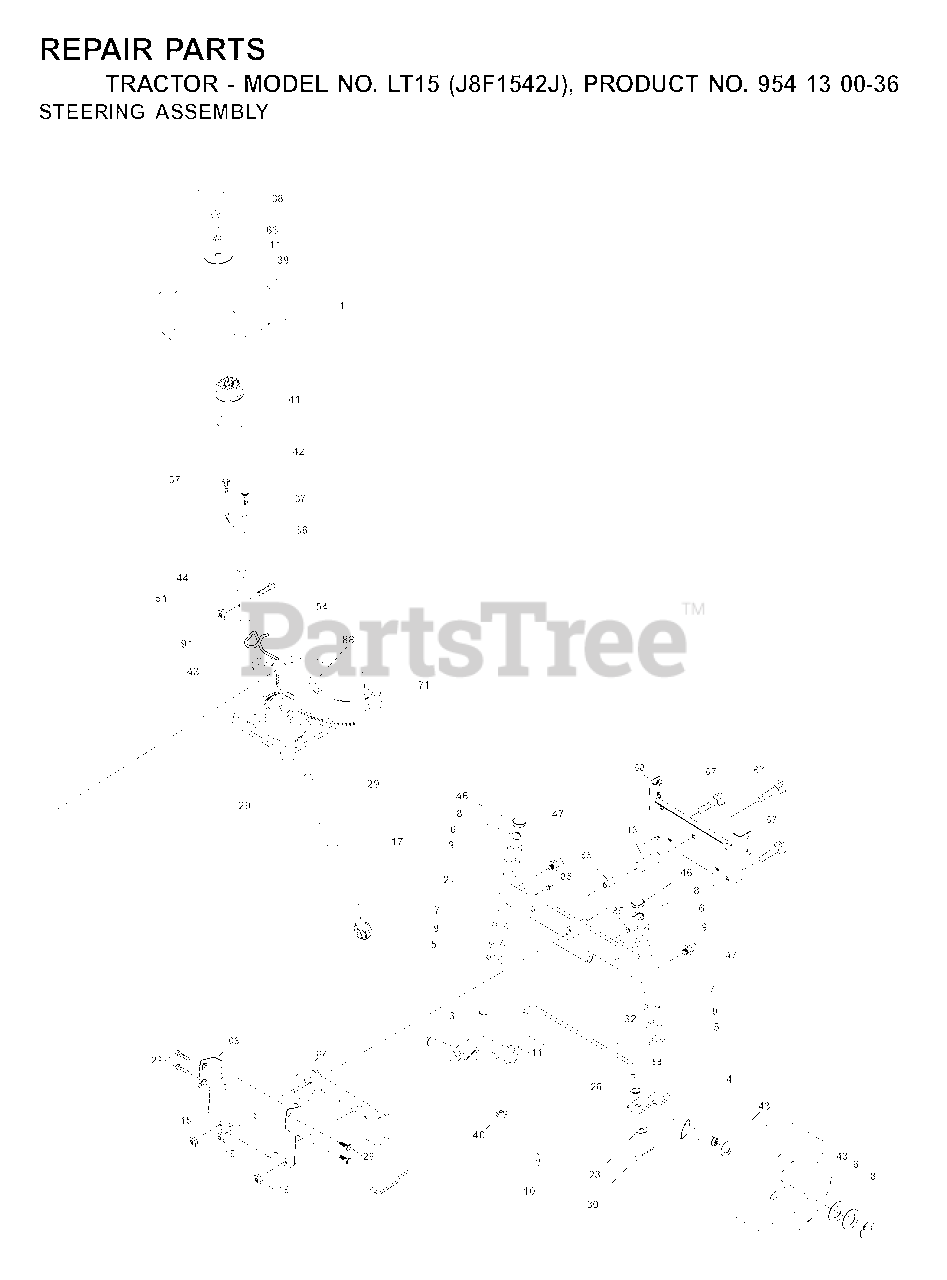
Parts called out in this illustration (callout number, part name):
2	AXLE ASSY
3	SPINDLE.ASM.LH.15"TIRES
4	SPINDLE.ASM.RH.15"TIRES
8	RING CLIP
9	BRNG T
10	DRAGLINK.15".TIRES.2001
11	WASHER, LOCK 3/8
13	TUBE, PIVOT AXLE
15	NUT
17	SHAFT ASM
26	BUSHING.DRAGLINK
28	WASHER
29	SCREW 3/8-16X3/4
30	COTTER PIN
32	TIE ROD
36	BUSHING, STEERING
39	WASHER 13/32 X 2-3/8 X 12 GA
40	GRIPCO NUT
41	STEERING WHEEL ADAPTOR
42	BOOT.STEERING.SHAFT.BLACK
44	EXT SHAFT STEERING
46	CAP.SPINDLE
47	ZERK M
51	NUT.71038.31-18.HEX.NYLOCK
54	BOLT.5/16-18X1-1/4 FULL.THREAD
63	BOLT
65	SPACER BRACE AXLE
67	BOLT
68	BRACE.AXLE.15"TIRES
71	STEERING ASM
82	BRACKET
85	FASTENER.XMAS.TREE
88	BOLT, SHOULDER 7/16-20
91	CLIP.STEERING
